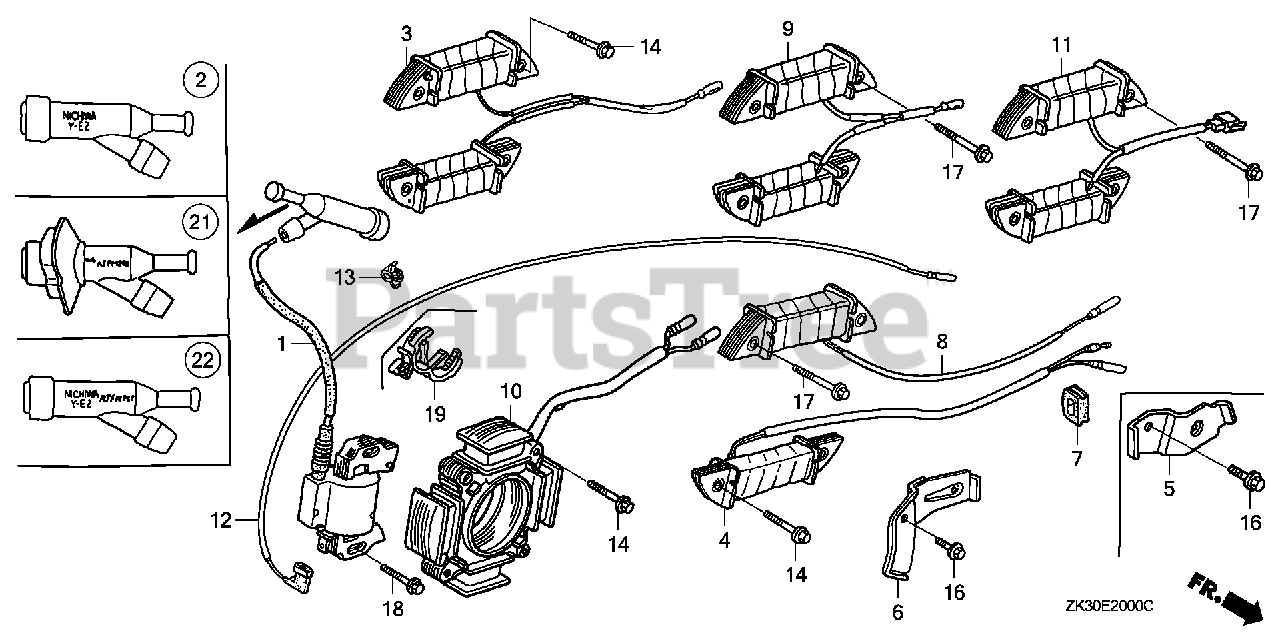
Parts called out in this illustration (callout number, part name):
1	COIL ASSY., IGNITION
6	CLAMP, WIRE
7	GROMMET, WIRE
8	COIL ASSY., CHARGE (1A)
12	WIRE, STOP SWITCH (430MM)
16	BOLT, FLANGE (6X12) (CT200)
17	BOLT, FLANGE (6X35) (CT200)
18	BOLT, FLANGE (6X28) (CT200)
22	CAP ASSY., NOISE SUPPRESSOR (NICHIWA Y-EZ RTFM256)
